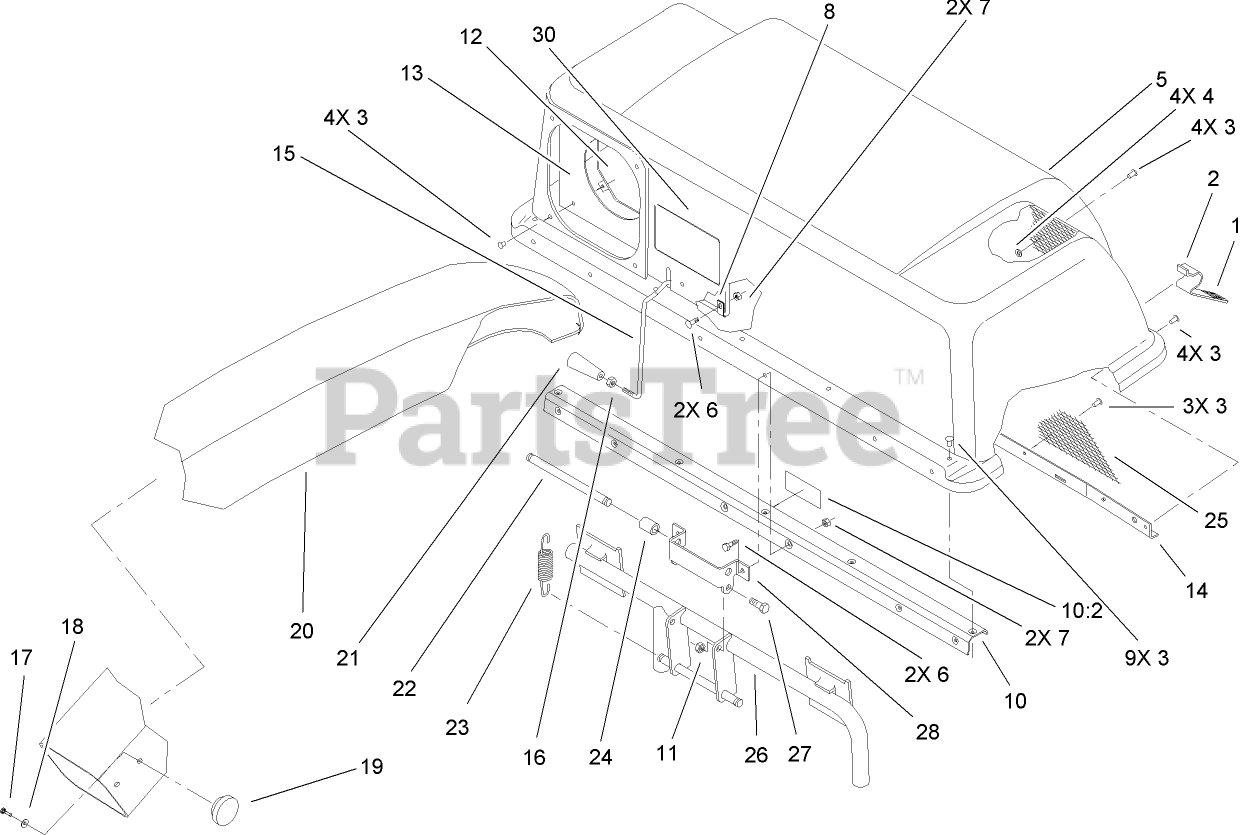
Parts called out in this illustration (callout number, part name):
2	LATCH-BAGGER, TOP
3	RIVET-BLIND
4	WASHER-FLAT
5	TOP-BAGGER
6	SCREW-HH
7	NUT-LOCK, NI
8	CLAMP
10	STIFFENER ASM
10:2	DECAL-CAUTION
11	NUT-LOCK, NI
12	CLAMP-SEAL
13	SEAL-CHUTE
14	SUPPORT-SCREEN
15	FEELER-FILL, BAG
16	NUT-JAM
17	SCREW-PPHTF
18	WASHER-PLAIN
20	CHUTE-DISCHARGE
21	HANDLE-TAPERED
22	PIN-SPRING
23	SPRING-EXTENSION
24	SPACER
25	SCREEN-BAGGER
26	FRAME ASM
27	SCREW-HH
28	HINGE-BAG, TOP
30	DECAL
